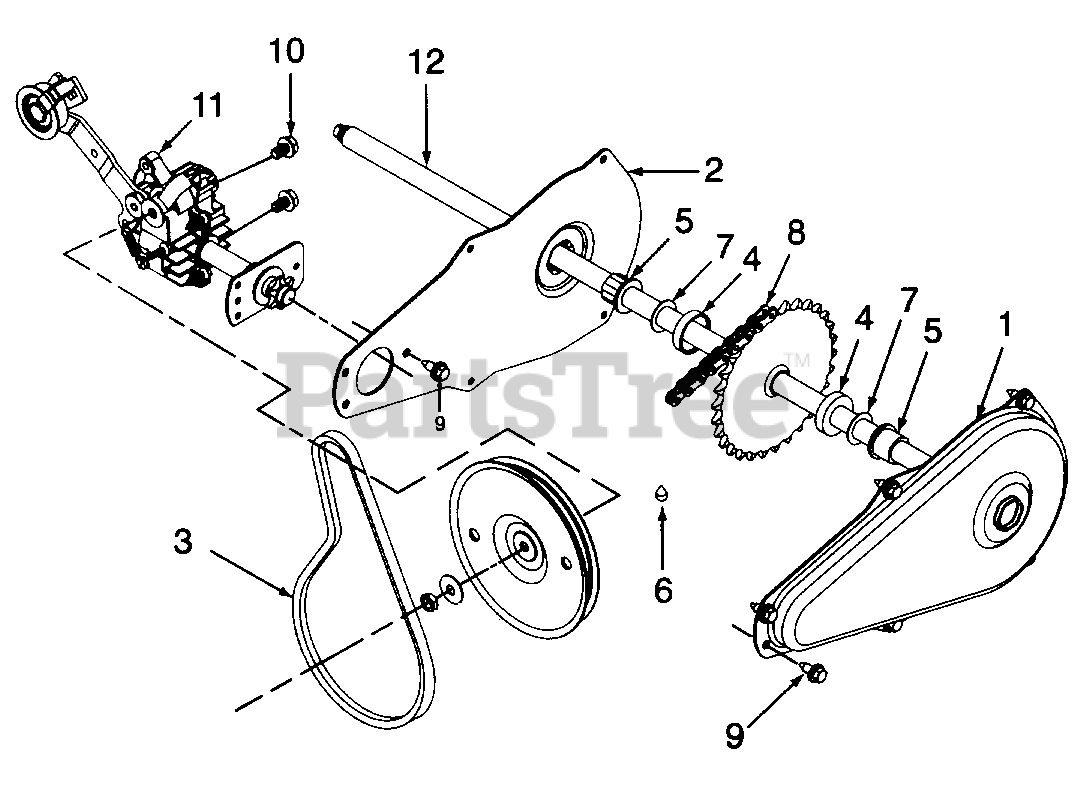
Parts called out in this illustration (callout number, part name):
3	V-Belt, 3/8 x 24.68
4	Spacer, .630 x 1.25 x .29
5	Bearing, Hex Flange, .631 ID
6	Grease, Benalene
7	Washer, Flat, 5/8 x 1.0
8	Chain, Endless, #41 x 50
9	Screw, Hex Wash Hd, 1/4-14 x .625
10	Screw, Hex Wash Hd Tapp 5/16-18 x .50
11	Complete Transmission Ass'y
12	Shaft Assembly, Axle
